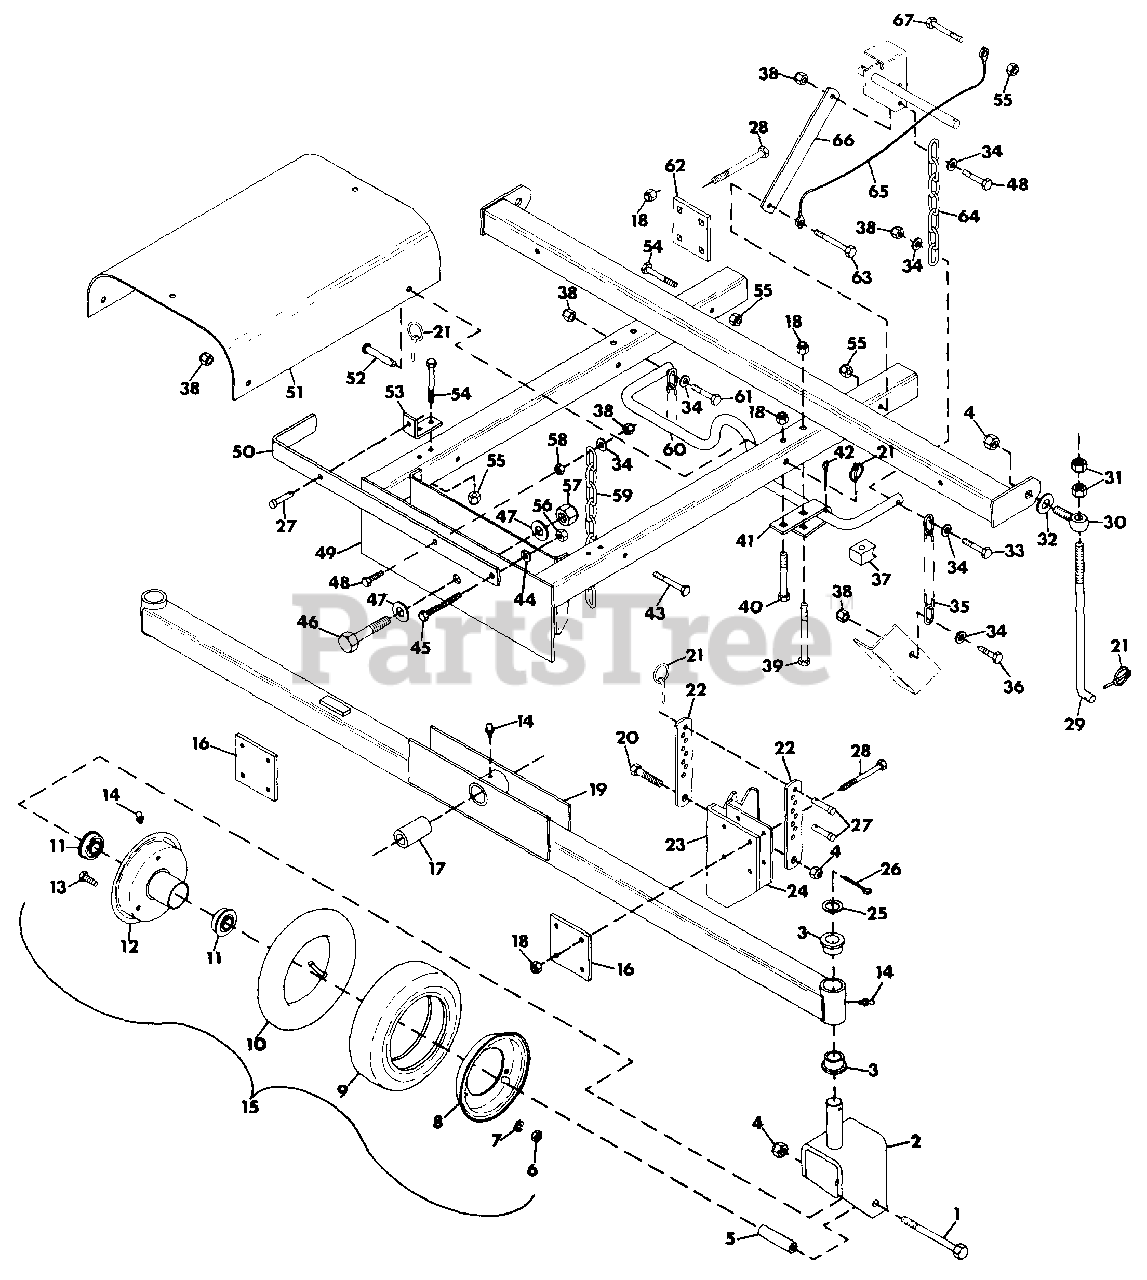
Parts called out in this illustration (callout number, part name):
1	BOLT, HEX 1/2-13X5.00
2	WELDMENT, CASTER FORK
3	BUSHING, PIVOT
4	NUT, LOCK 1/2-13
5	BUSHING, WHEEL .520X.750X3.312
6	NUT, HEX 3/8-24
7	WASHER, LOCK 3/8 SP HEAVY
8	WHEEL, HALF PLAIN
9	TIRE, GAUGE WHEEL
10	TUBE, INNER
11	BEARING, GAUGE WHEEL
12	WHEEL, HALF WITH TUBE
13	BOLT, HEX 3/8-24X.75
14	FITTING, LUBE 1/4-28
15	WHEEL, GAUGE
16	PLATE, ADJUSTMENT CLAMP
17	TUBE, PIVOT
18	NUT, LOCK 3/8-16
19	WELDMENT, AXLE
20	BOLT, HEX 1/2-13X2.00
21	KLIK PIN
22	STRAP, ADJUSTMENT
23	PLATE, HEIGHT ADJUSTMENT-L.H.
23	PLATE, HEIGHT ADJUSTMENT-R.H.
24	PLATE, HEIGHT ADJUSTMENT-L.H.
24	PLATE, HEIGHT ADJUSTMENT-R.H.
25	RACE, BEARING THRUST
26	PIN, COTTER 3/16X1.62
27	PIN, CLEVIS
28	BOLT, HEX 3/8-16X3.25
29	ROD, HEIGHT ADJUSTMENT
30	BOLT, EYE
31	NUT, JAM 1/2-13 HEX
32	WASHER, FLAT .500X1.250X.083
33	BOLT, HEX 5/16-18X1.75
34	WASHER, FLAT .406X.812X.065
35	CHAIN, LIFT
36	BOLT, HEX 5/16-18X1.00
37	STOP, NYLON
38	NUT, LOCK 5/16-18
39	BOLT, HEX 3/8-16X4.00
40	BOLT, HEX 3/8-16X3.00
41	BRACKET, AXLE SUPPORT
42	PIN, COTTER 1/8X1.25
43	BOLT, HEX 5/16-18X2.50
44	WASHER, LOCK 3/8
45	BOLT, 3/8-16X3 SPECIAL
46	BOLT, HEX 3/4-10X4.50
47	WASHER, FLAT .812X.469X.130
48	BOLT, HEX 5/16-18X1.25
49	WELDMENT, MOWER FRAME
50	BAR, LIFT
51	GUARD, PTO SHAFT
52	PIN, CLEVIS 3/8X2.62
53	BRACKET, LIFT PIVOT
54	BOLT, 5/16-24X2.75
55	NUT, LOCK 5/16-24
56	NUT, JAM 3/8-16
57	NUT, LOCK 3/4-10
58	NUT, JAM 5/16-18
59	CHAIN, HEIGHT ADJ.
60	ARM, PIVOT
61	BOLT, HEX 5/16-18X1.50
62	PLATE, ATTACHMENT CLAMP
63	BOLT, 5/16-24X3.5
64	CHAIN, LIFT
65	CABLE, STOP
66	BAR, DECK LIFT
67	BOLT, 5/16-24X2.25
NS	DECAL, PRO MASTER-50
